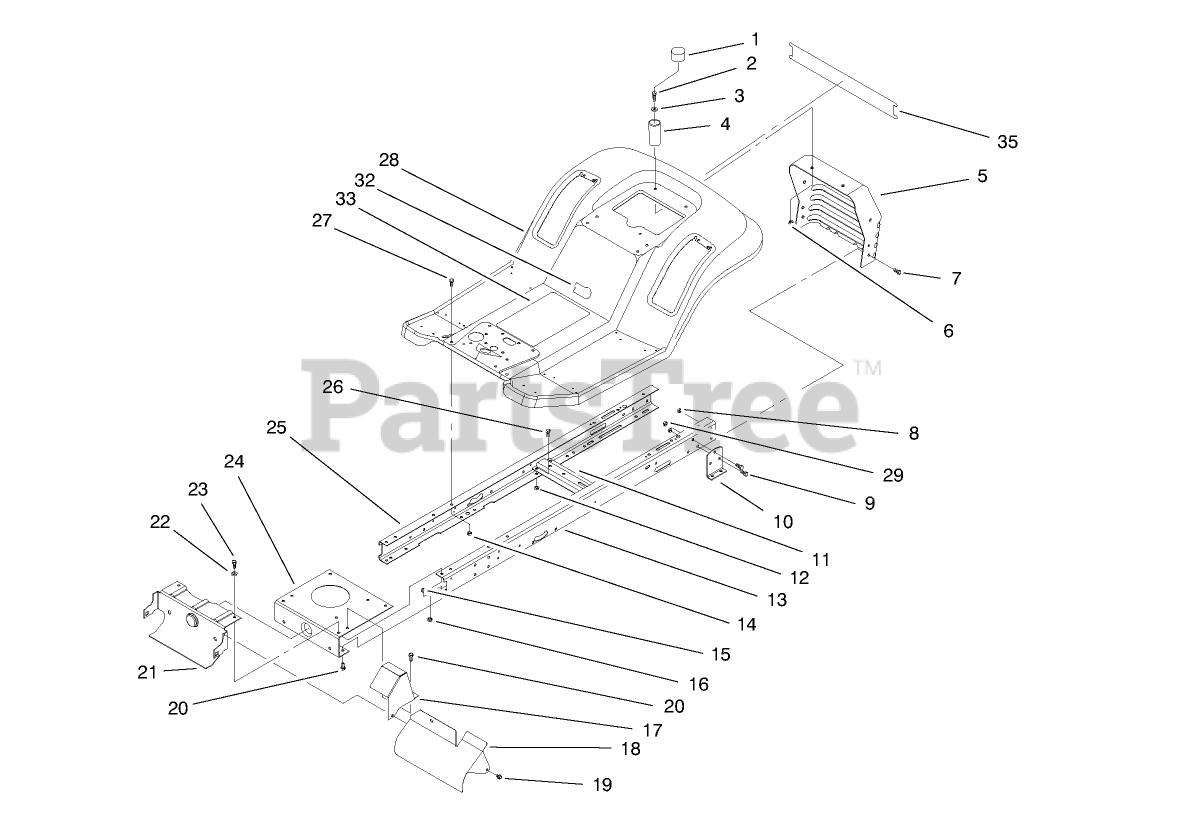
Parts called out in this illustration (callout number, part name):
1	CAP-PROTECTOR
2	SCREW-HH
3	WASHER-PLAIN
4	SPRING-COMPRESSION
6	NUT-LOCK, NI
7	SCREW-HH
8	NUT-LOCK, NI
9	SCREW-HH
10	BRACKET-TRANSAXLE, MOUNTING
11	BRACKET-IDLER PIVOT
12	NUT-LOCK, NI
14	NUT-LOCK, NI
15	NUT-LOCK, NI
16	NUT-LOCK, NI
17	SHIELD-EXHAUST PIPE
18	SHIELD-MUFFLER
19	SCREW-HWHTF
20	SCREW-HH
22	WASHER-PLAIN
23	SCREW-HH
24	PLATE-MOUNTING, ENGINE
26	SCREW-HH
27	SCREW-HH
29	NUT-LOCK, NI
32	DECAL - USA
